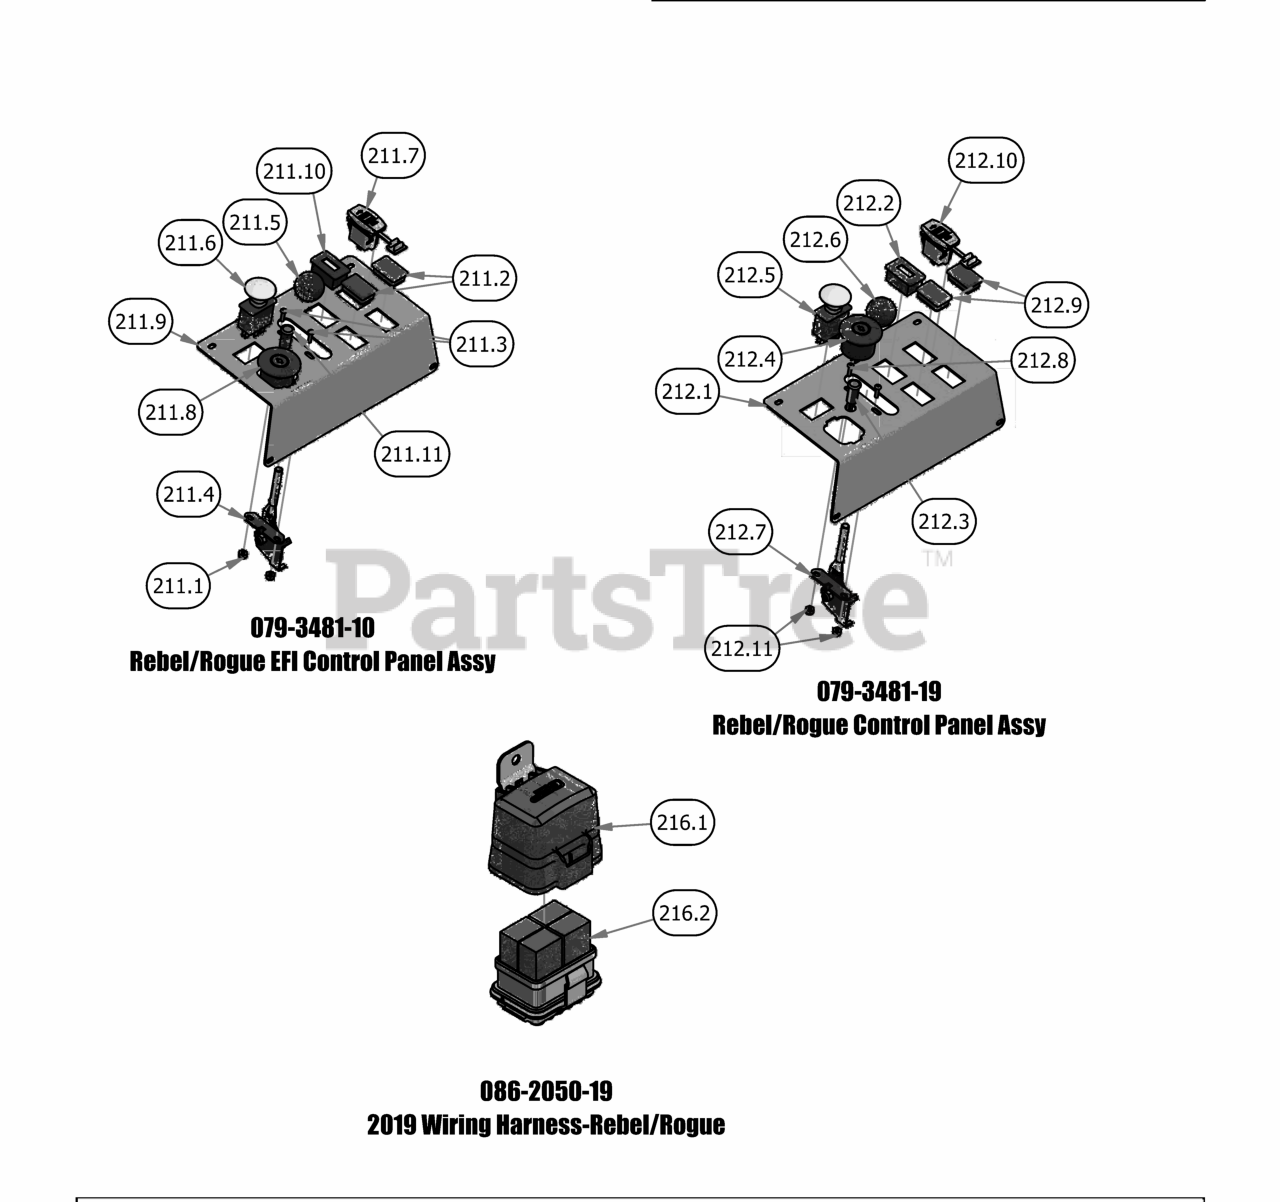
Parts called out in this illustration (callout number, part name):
211.1	10-24 Nylon Insert Locknut Zinc Orange Nylon
211.2	Light Plug
211.3	10-24 X 5/8 BS Button Head Bolt
211.4	Universal Throttle
211.5	Throttle Knob
211.6	PTO Switch
211.8	Ignition Switch
211.9	2019 Outlaw Control Panel
211.10	Tachometer
212.1	2019 Outlaw Control Panel
212.2	Tachometer
212.4	Ignition Switch
212.5	PTO Switch
212.6	Throttle Knob
212.7	Universal Throttle
212.8	10-24 X 5/8 BS Button Head Bolt
212.9	Light Plug
212.11	10-24 Nylon Insert Locknut Zinc Orange Nylon
216.1	Relay Block Cover Replacement Kit
